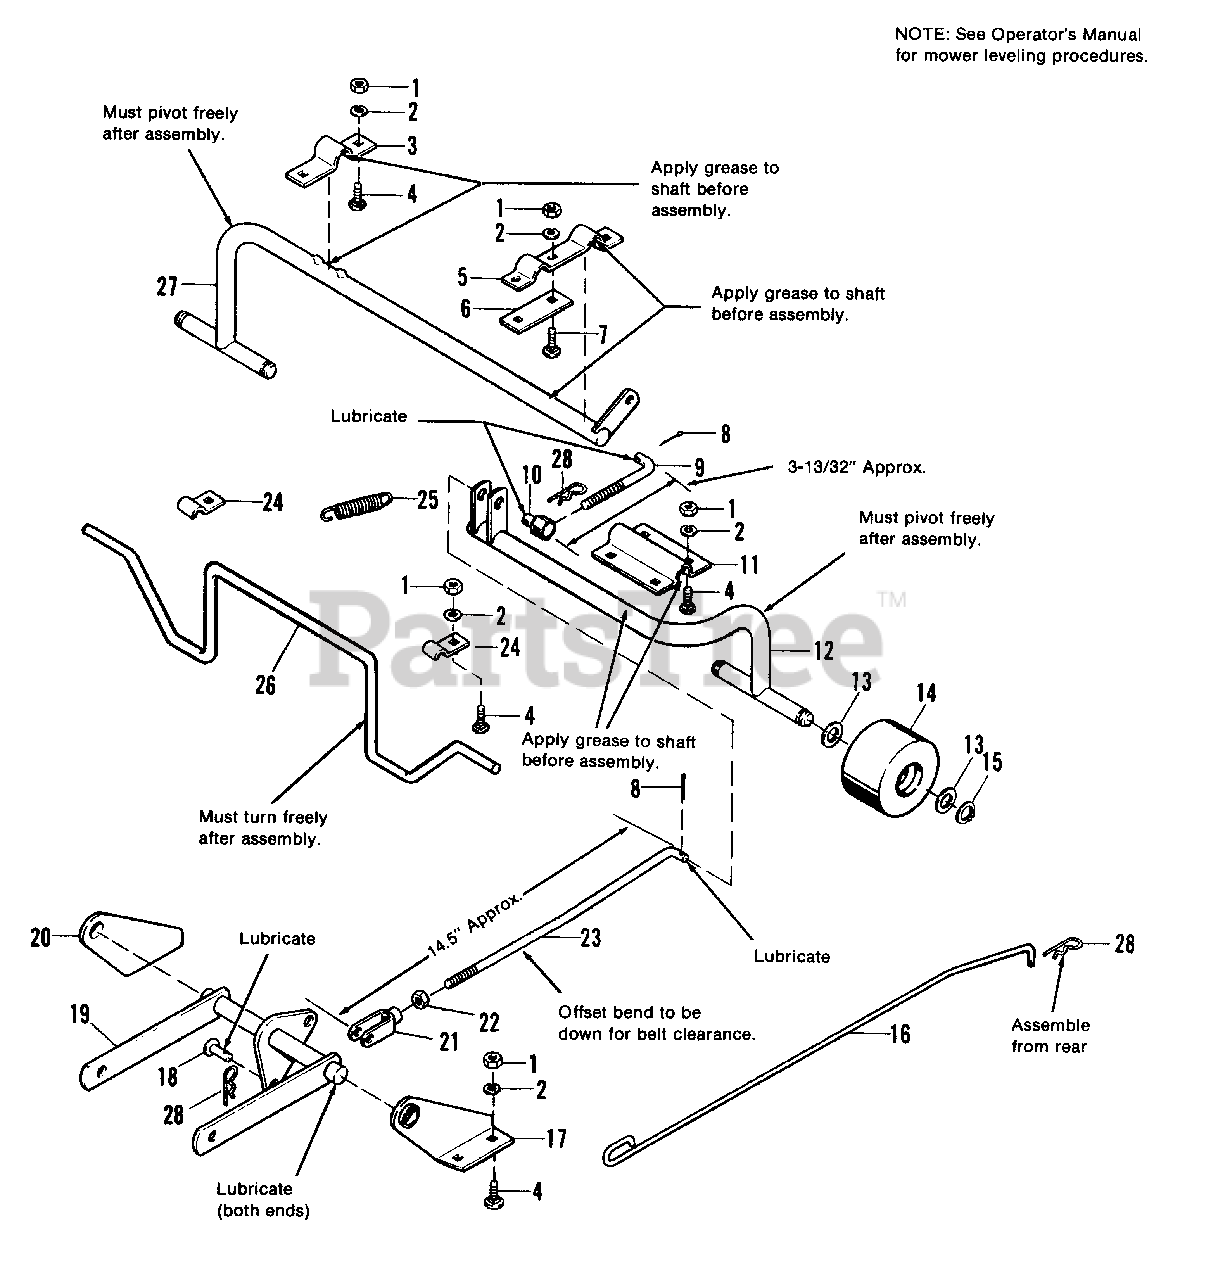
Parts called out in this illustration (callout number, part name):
1	NUT, Hex, 5/16-18
2	LOCKWASHER, 5/16
4	BOLT, Carriage, 5/16-18 x 3/4
5	CLAMP, Wheel Support
7	BOLT, Carriage, 5/16-18 x 1
8	PIN, cotter 3/32 x 3/4
12	WHEEL SUPPORT ASSY., L.H.
13	WASHER, 41/64
15	RING, Retainer
16	ROD, Brake
17	BRACKET, Front, L.H.
19	SUPPORT ARM ASSY.
20	BRACKET, Front, R.H.
21	CLEVIS, Adjusting
22	NUT, Hex, 3/8-16
23	ROD, Link
26	BRAKE, Mower
27	WHEEL SUPPORT ASSY., R.H.
28	CLIP, Hairpin
